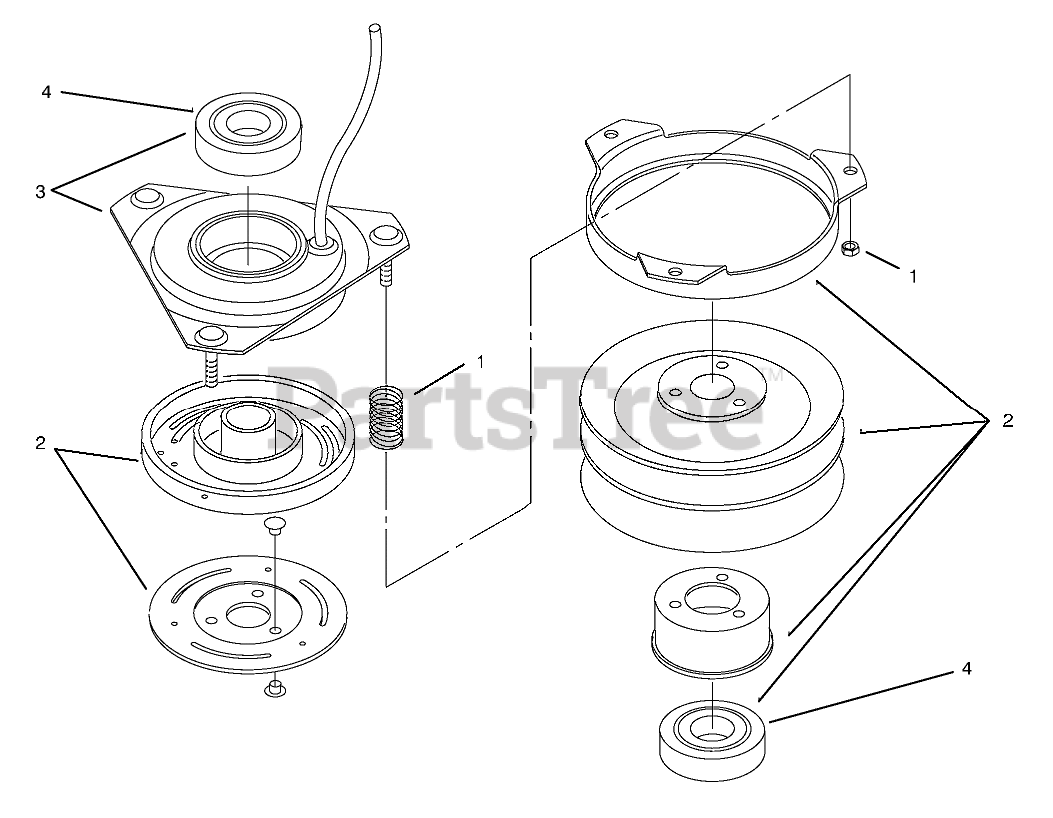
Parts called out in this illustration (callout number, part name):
1	ACCESSORY PKG SRVC PART
2	ASM - ROTOR/ARMATURE
3	FIELD ASSY (SRVC PART)
4	BEARING-ELEC CLUTCH
